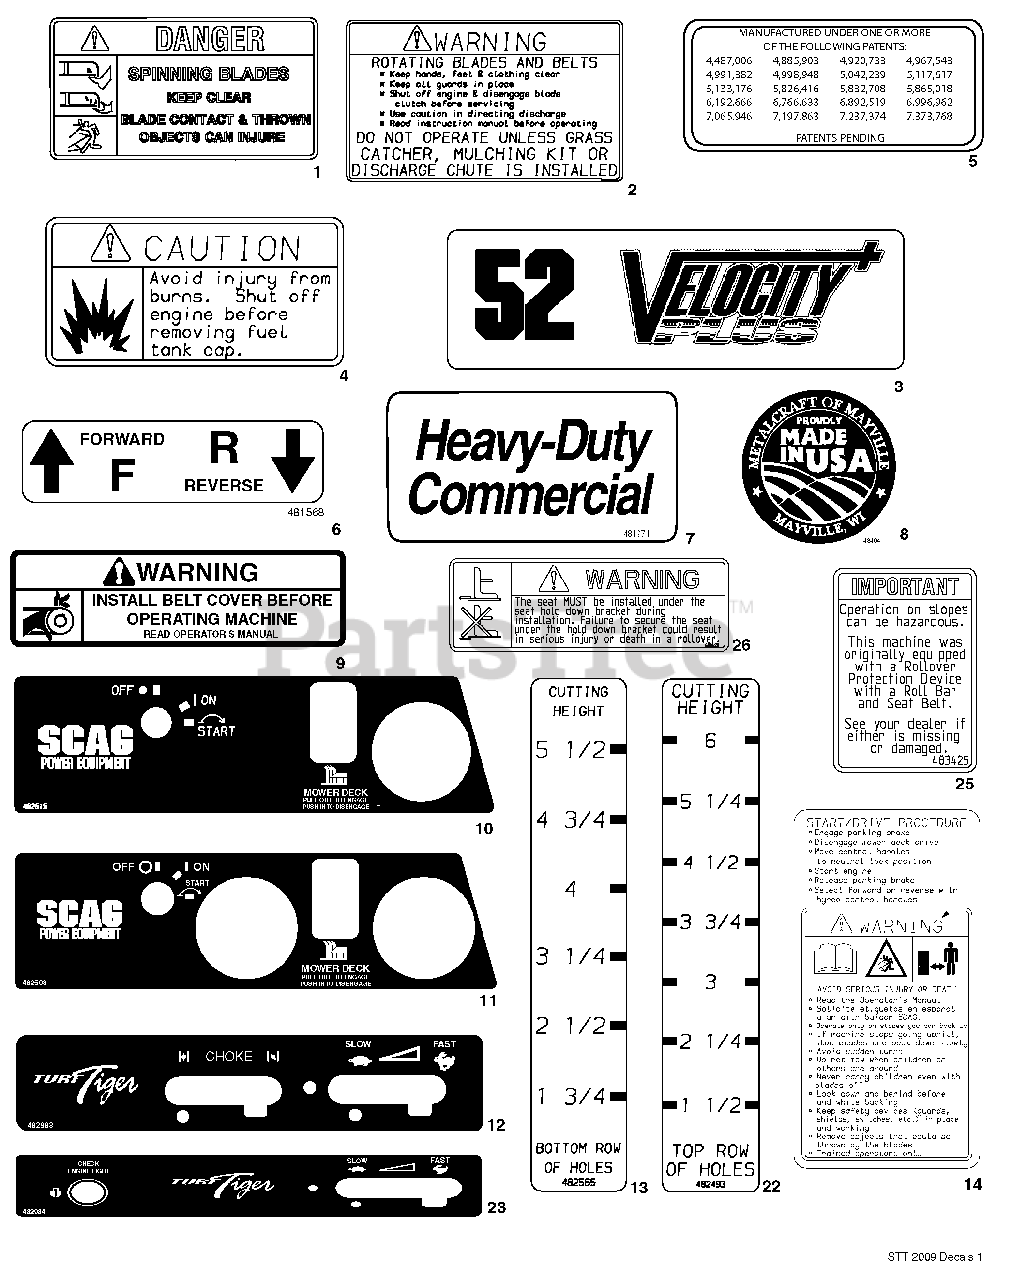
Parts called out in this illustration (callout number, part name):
1	Decal, Danger - Spinning Blades
2	Decal, Warning - Rotating Blades
3	Decal, 52 Velocity Plus
4	Decal, Fuel Tank
5	Decal, Patents
6	Decal, Traction Control
7	Decal, Heavy-Duty Commercial
8	Decal, Metalcraft-Made In USA
9	Decal, Belt Cover
10	Decal, Instrument Panel - Upper (Air-Cooled)
11	Decal, Instrument Panel - Upper
12	Decal, Instrument Panel-Lower
13	Decal, Cutting Height - Lower
14	Decal, Start/Drive Procedure
22	Decal, Cutting Height - Upper
23	Decal, Instrument Panel - Lower
24	Decal, ROPS
25	Decal, ROPS
26	Decal, Warning Seat Hold Down
